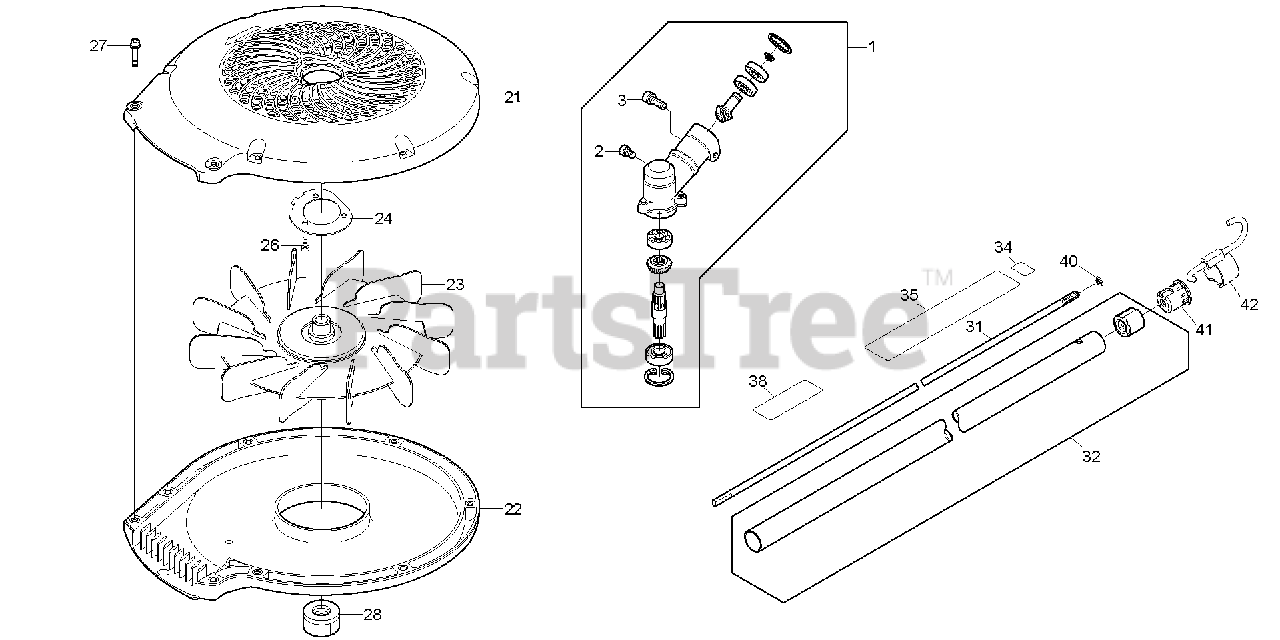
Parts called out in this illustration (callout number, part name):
1	CASE B, GEAR
2	BOLT, TORX (6X8)
3	BOLT, TORX (6X20)
21	HOUSING (UPPER)
22	HOUSING (BOTTOM)
26	BOLT, TORX (5X20)
27	BOLT-WASHER, TORX (5X23)
28	NUT, HEX. (10MM)
31	SHAFT, DRIVE
34	MARK, ARROW
35	MARK, CAUTION
38	MARK, EMBLEM (SSBL)
